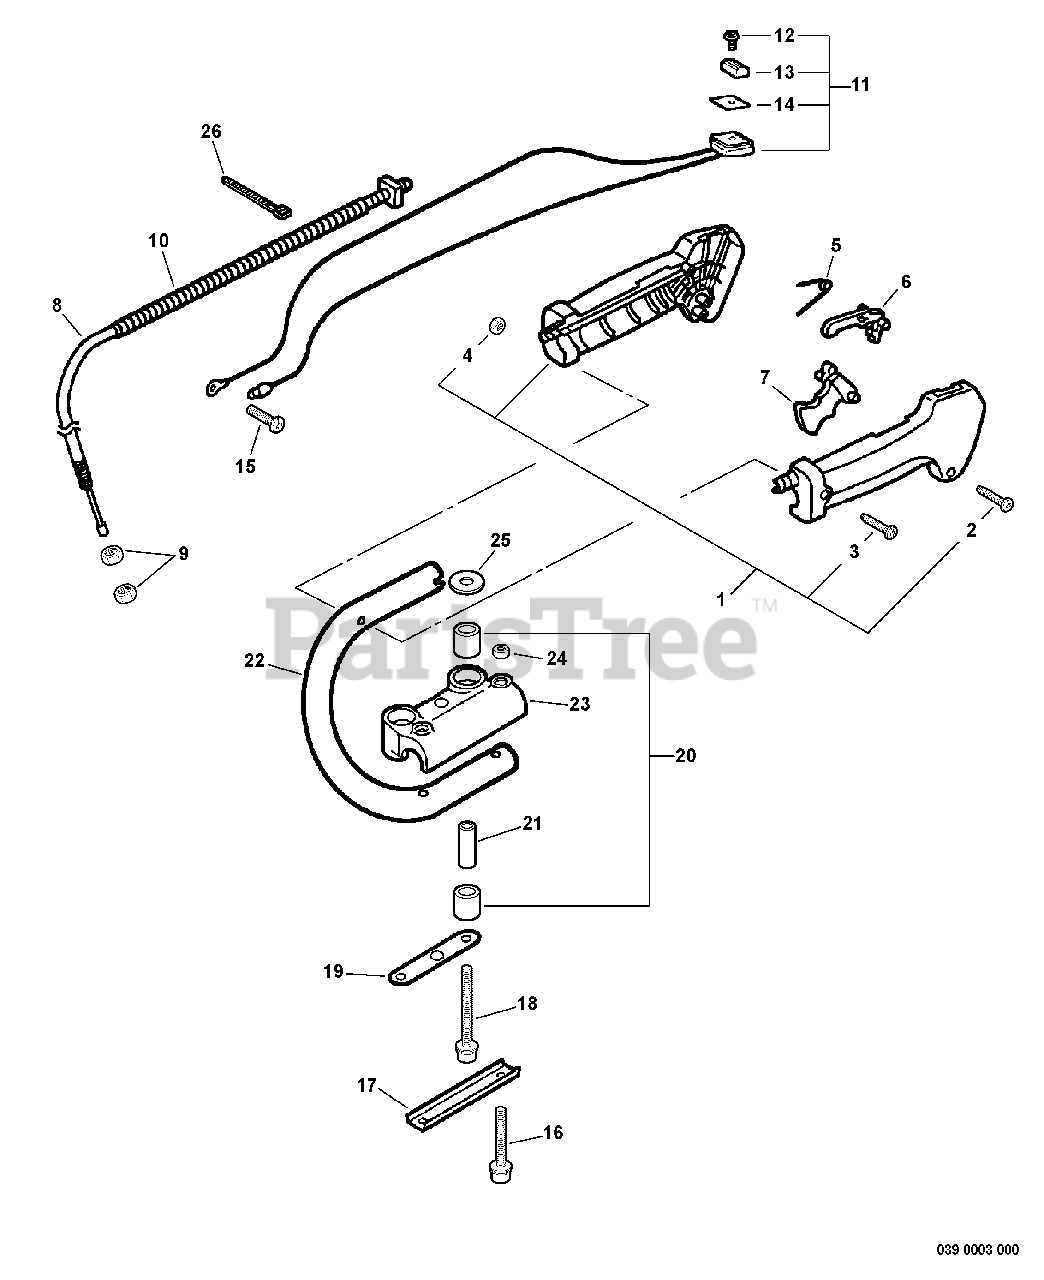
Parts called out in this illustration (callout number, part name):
1	CONTROL HANDLE KIT
2	SCREW 3×25
3	SCREW 5×30
4	NUT M5
5	SPRING, TORSION
6	LOCKOUT, THROTTLE
7	TRIGGER, THROTTLE
8	CABLE, THROTTLE
10	TUBE, FLEXIBLE
11	SWITCH, ON-OFF
12	SCREW 3×10
13	KNOB, SWITCH - ORANGE
14	LABEL, SWITCH
15	SCREW 5×10
16	BOLT M5×35
18	BOLT 5×45
19	PLATE, EYE
21	SPACER
22	HANDLE, REAR
23	BRACKET, HANDLE - UPPER
24	NUT M5
25	WASHER 5.5×18×1
26	STRAP, TIE
